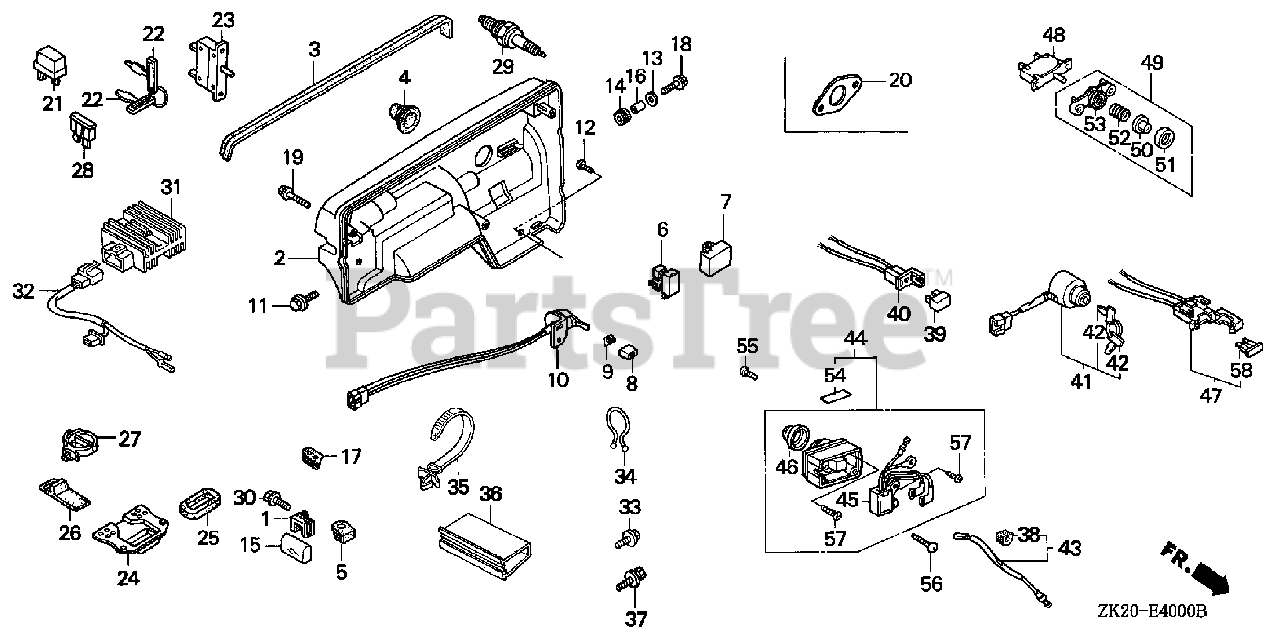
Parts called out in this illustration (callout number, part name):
1	CLIP, WIRE
39	RECTIFIER ASSY., SILICON (STANLEY)
40	CONNECTOR
41	SWITCH ASSY., COMBINATION
42	KEY
47	CASE, FUSE
48	PROTECTOR, CIRCUIT (1.0A)
49	LENS ASSY., PROTECTOR
50	LENS
51	CAP, LENS
52	SPRING, COIL
53	HOLDER, LENS
55	SCREW, GLOVE BOX
58	FUSE, BLADE (5A)
